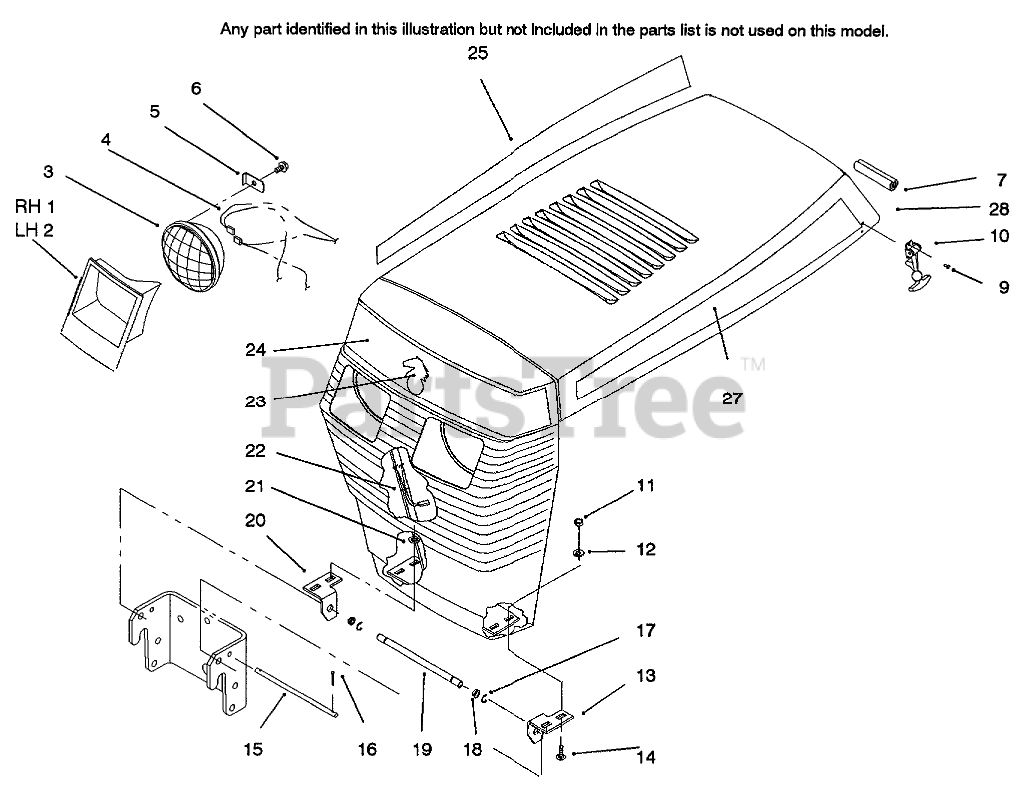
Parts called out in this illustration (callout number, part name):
1	BEZEL-HEADLIGHT, LH
2	BEZEL-HEADLIGHT, RH
3	HEADLAMP
4	HARNESS-HEADLIGHT
5	LOCK-HEADLIGHT
6	SCREW-HWH
9	RIVET-POP
9	CLIP
10	HANDLE ASM
11	NUT-LOCK, NI
12	WASHER-FLAT
13	BRACKET-GRILL, LH
14	SCREW-CARR
15	ROD-HOOD STOP
16	PIN-COTTER
17	BUSHING-NYLINER
18	RING-RETAINING
19	ROD-GRILL PIVOT
20	BRACKET-GRILL, R H
22	TIE-CABLE
23	LOGO - HORSEHEAD
24	DECAL-FRONT HOOD, TOP
25	DECAL - RH HOOD TOP
27	DECAL - LH HOOD TOP
28	Hood
